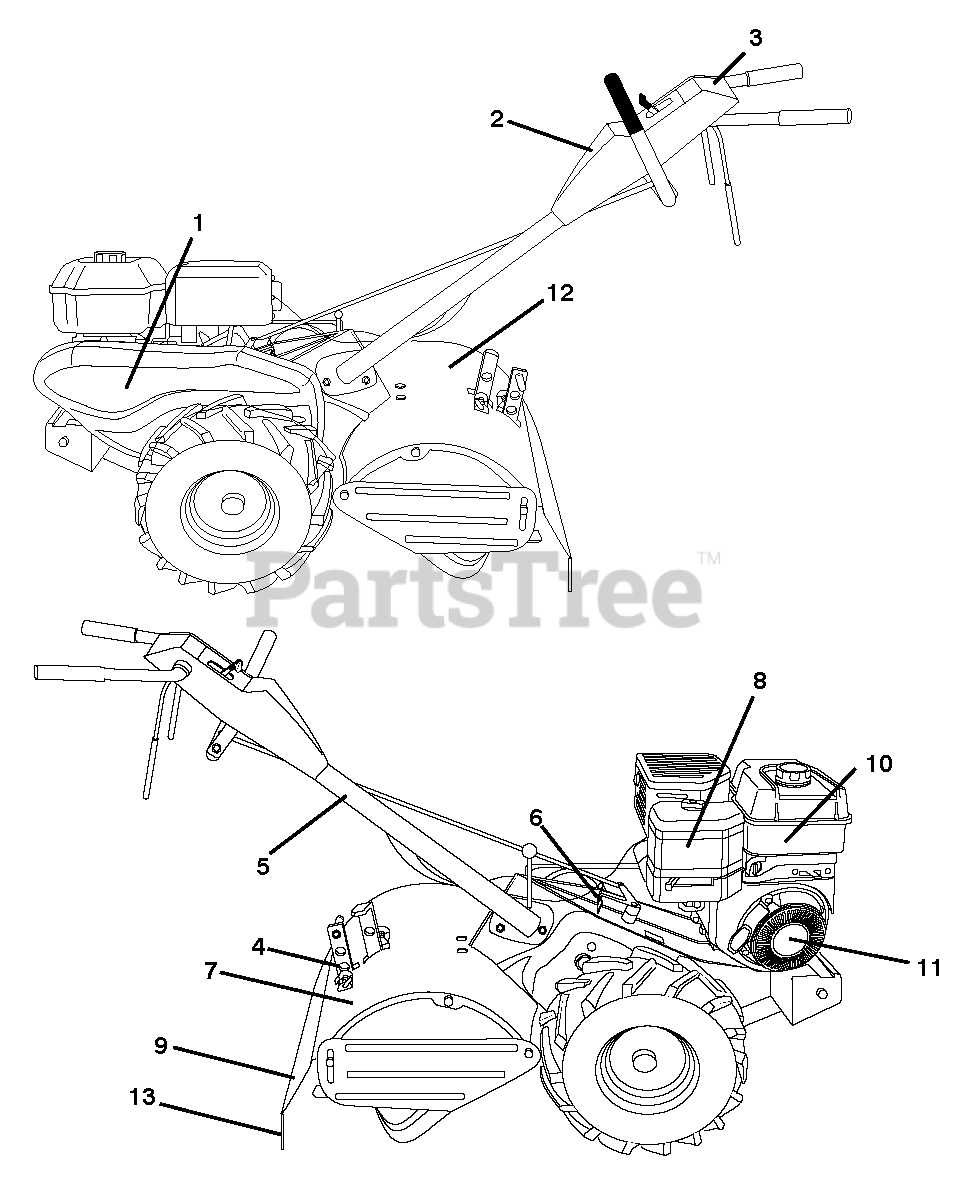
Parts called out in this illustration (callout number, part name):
3	Decal, Console DRT HU
4	Decal, Shield Tine 17 D
5	DECAL, HAND PLACEMENT
6	DECAL.SHIFT.INDICATOR.DRT
8	DECAL.B&S.7HP
10	DECAL.ENG.INTK.B&S.206CC
11	DECAL.REWIND
13	DECAL
